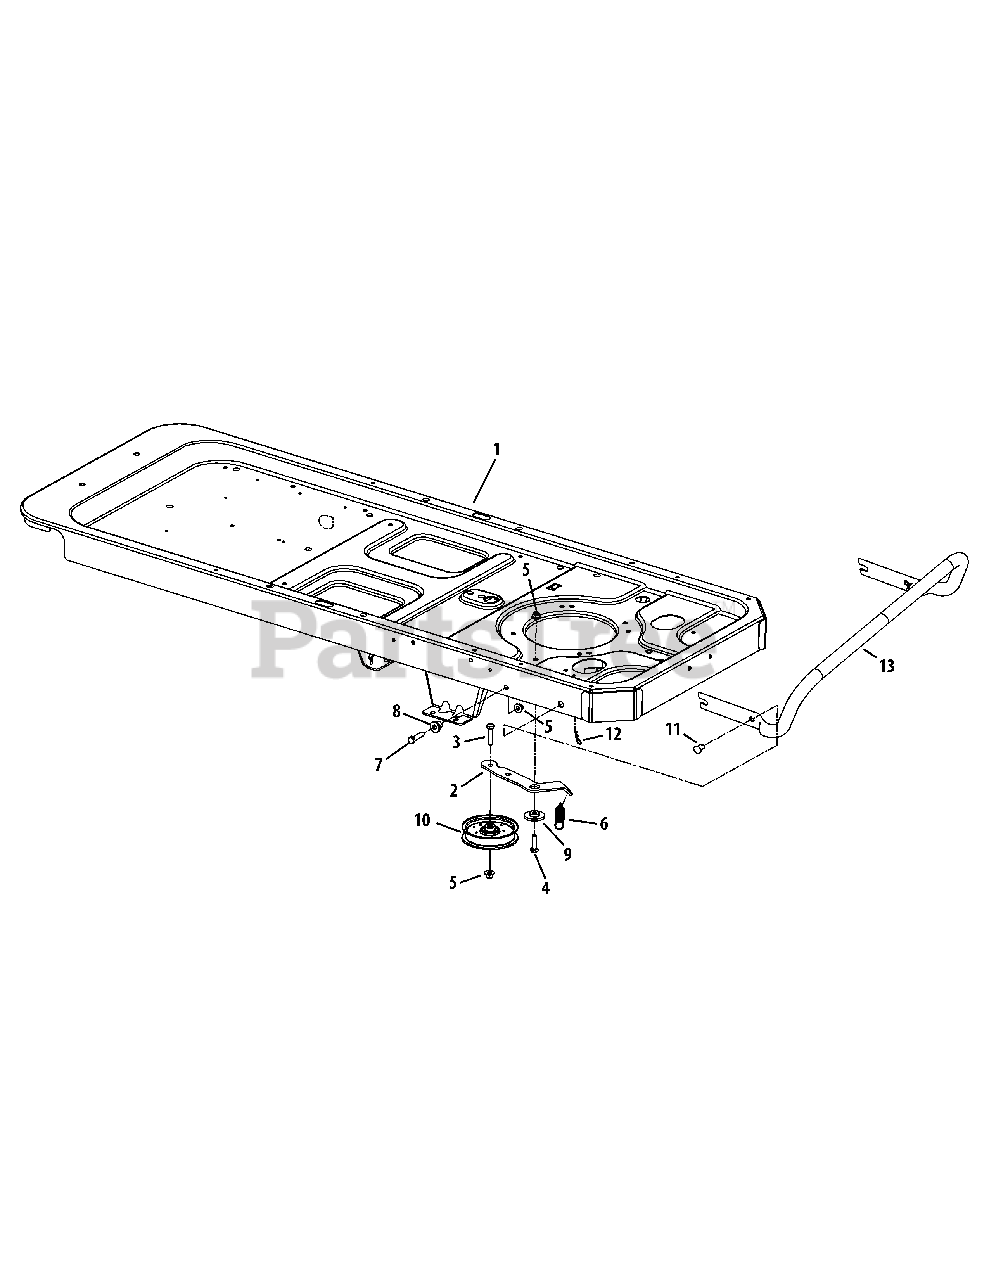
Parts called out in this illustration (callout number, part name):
1	Frame Assembly - Black
1	Frame Assembly - Red
3	Hex Screw, 3/8-16 x 1.5
4	Hex Screw, 3/8-16 x 1.25
5	Flange Nut, 3/8-16
6	Extension Spring, .75 x 5.06
7	Hex Screw, 3/8-16 x 1.5, GR2
8	Shoulder Spacer, .39 x 1.0 x .7
9	Shoulder Spacer, .884 x .19
10	Idler Pulley, 4.25 Dia.
11	Clevis Pin, .50 Dia. x .78 Lg.
12	Cotter Pin, .080 x 1.5625
13	Bumper
